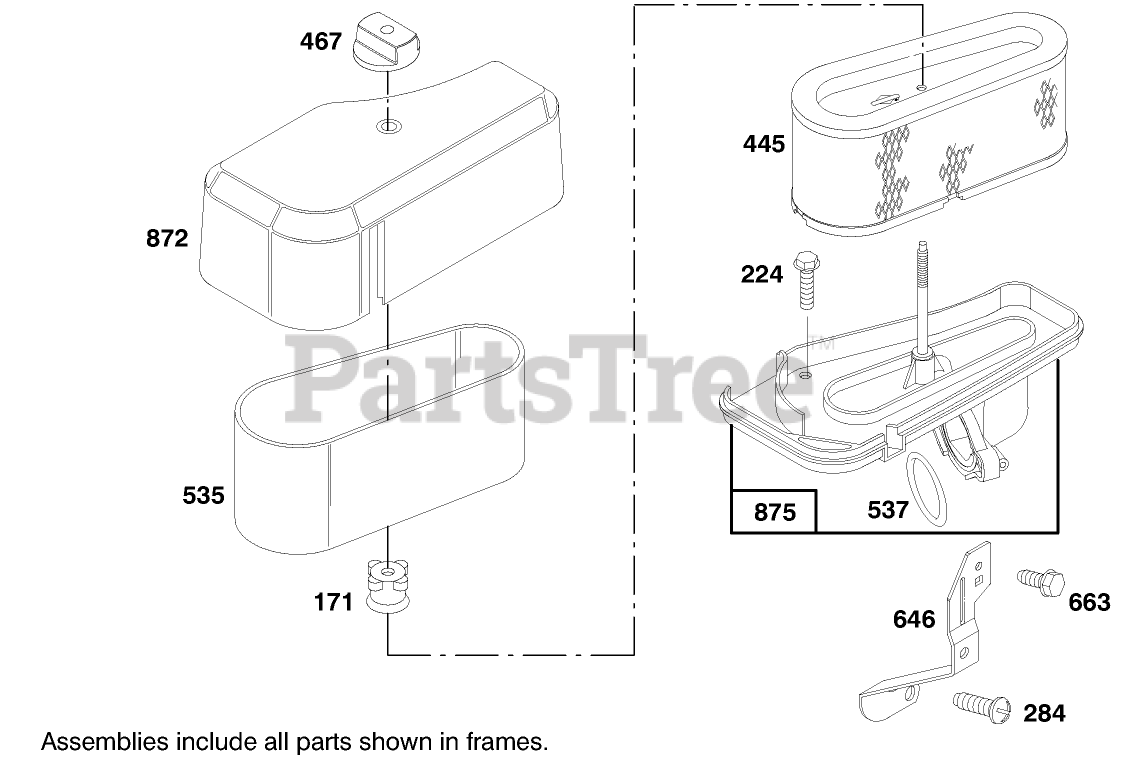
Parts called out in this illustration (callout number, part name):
224	Screw-Sem
284	Screw-Pan Head
445	Filter-Air
535	Filter-Air
537	O-Ring
646	Brace-Air Cleaner
663	Screw
872	Cover-Air Cleaner
875	Base-Air Cleaner
